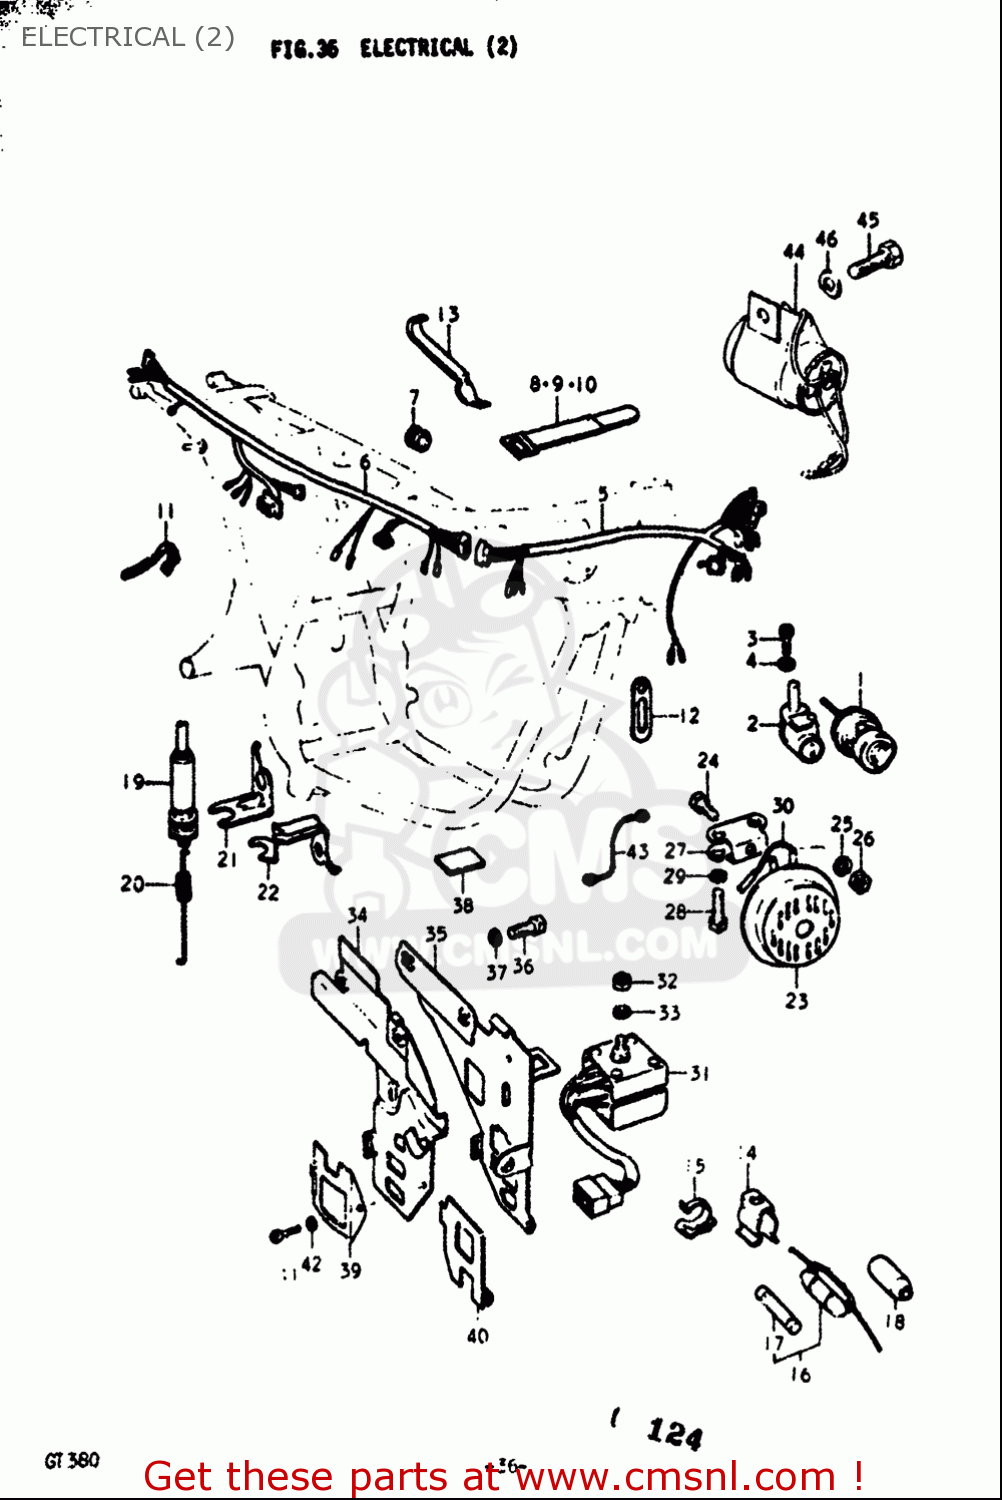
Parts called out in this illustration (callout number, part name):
1	SWITCH ASSY,IGNITION
2	LOCK ASSY,STEERING
3	SCREW
4	WASHER,LOCK
8	CLAMP
9	CLAMP
10	CLAMP
11	CLAMP
12	CLAMP(L:65)
16	CASE ASSY,FUSE
17	FUSE(20A)
19	SWITCH ASSY,STOP LAMP
20	SPRING
21	BRACKET, BRAKE LAMP SWITCH
23	HORN ASSY
24	BOLT
25	WASHER,LOCK
26	NUT
28	BOLT
29	WASHER,LOCK
30	WIRE,HORN LEAD
31	RECTIFIER ASSY
32	NUT
33	WASHER,LOCK
36	BOLT
37	WASHER,LOCK
38	CUSHION(30X50X3)
41	SCREW
42	WASHER,LOCK
43	LEAD WIRE
44	RELAY,TURN SIGNAL
45	BOLT
46	WASHER,LOCK
